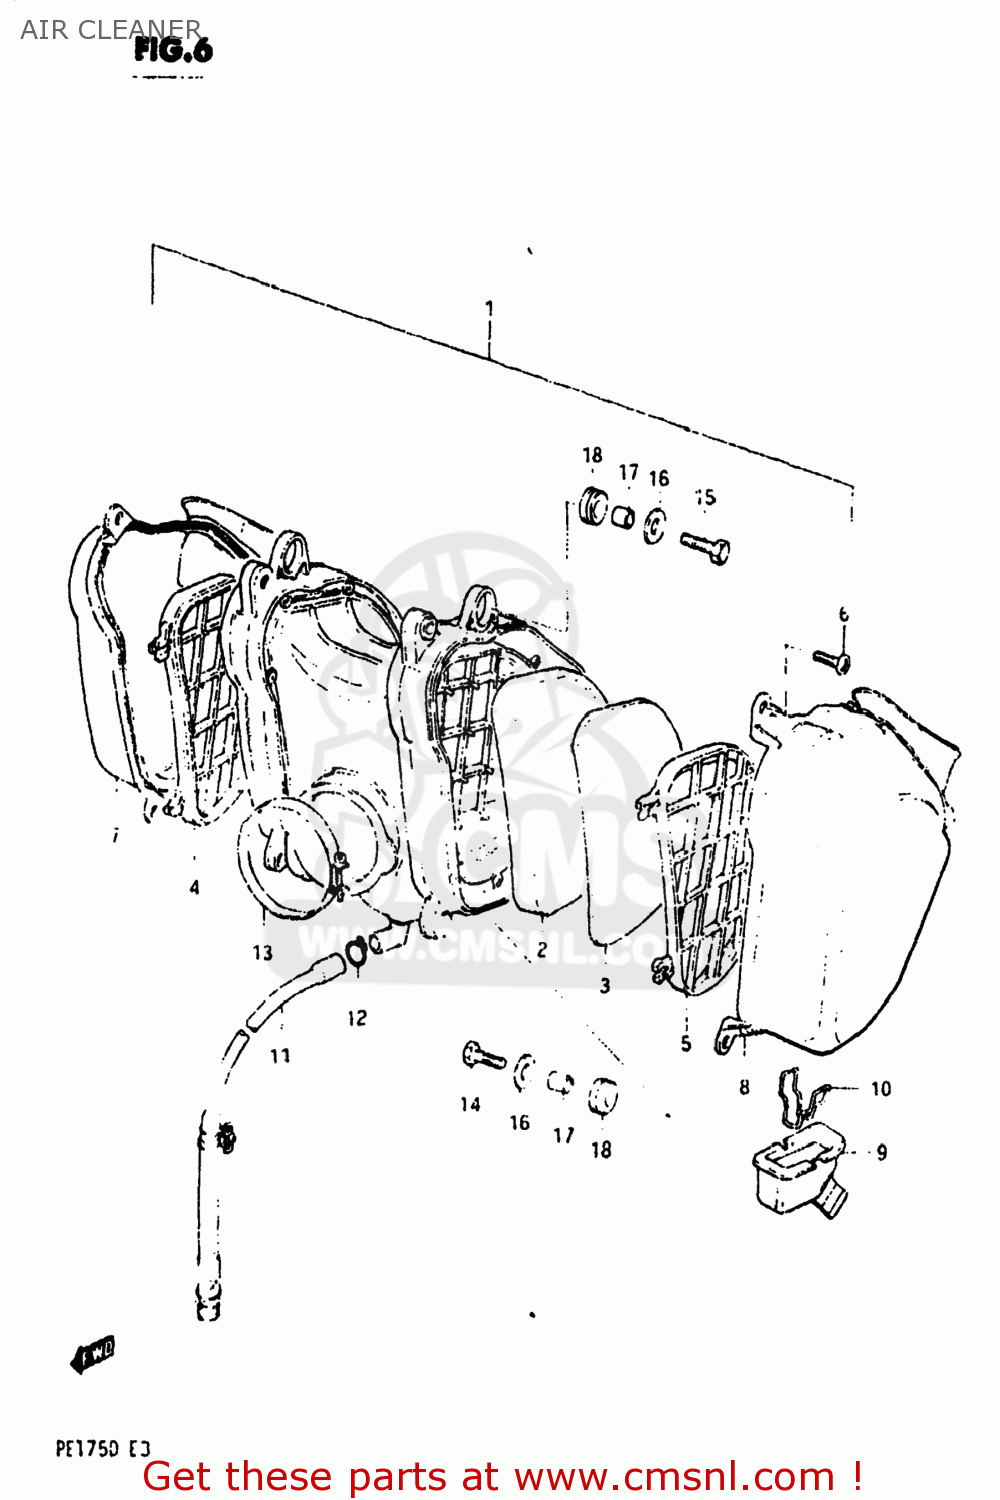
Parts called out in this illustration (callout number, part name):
1	CLEANER ASSEMBLY,AIR
2	FILTER
3	FILTER,2ND
4	HOLDER,AIR CLEANER,RIGHT
5	HOLDER,AIR CLEANER,LEFT
6	SCREW
7	CAP,AIR CLEANER,RIGHT
8	CAP,AIR CLEANER,LEFT
9	DRAIN,AIR CLEANER
10	DRAIN STOPPER
11	DRAIN TUBE
12	CLIP
13	CLAMP
14	BOLT
15	BOLT, UPPER
16	WASHER
17	SPACER (7X9X7)
18	CUSHION
